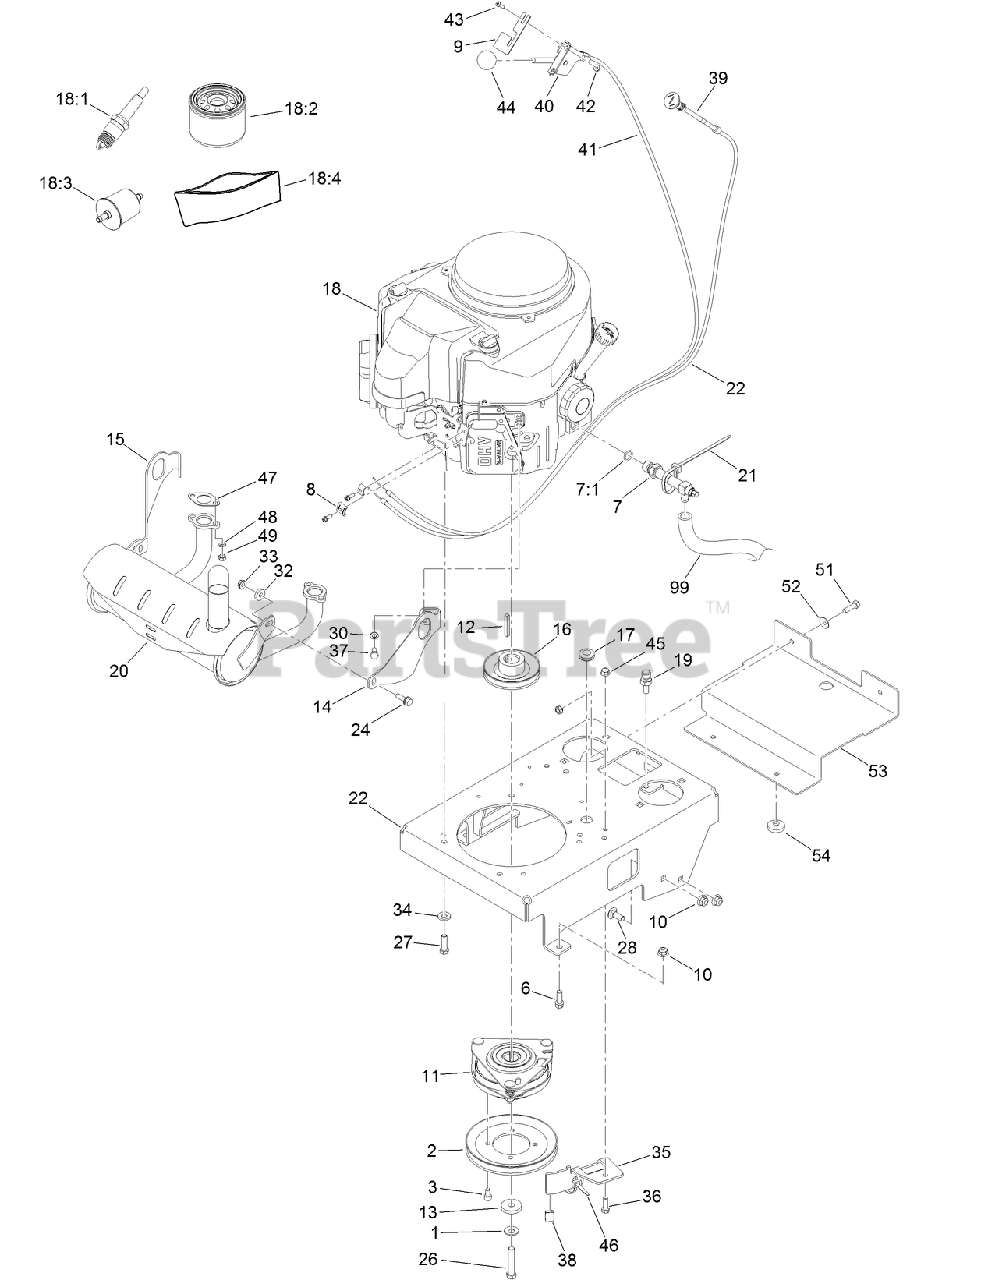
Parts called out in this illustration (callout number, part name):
1	WASHER-SPRING
2	PULLEY
3	SCREW-HSH
7	DRAIN-OIL, VALVE, KAW
7:1	O-RING
8	CLAMP-CABLE
9	PLATE-SET, THROTTLE
10	NUT-HF, NI
11	CLUTCH/BRAKE ASM
12	KEY-SQUARE
13	WASHER
14	BRACKET-MUFFLER, LH
15	BRACKET-MUFFLER, RH
16	PULLEY
17	GROMMET
18:1	SPARK PLUG
18:2	FILTER-OIL
18:3	FILTER-FUEL
18:4	ELEMENT-FILTER, AIR
19	ANCHOR-SPRING, SHORT
20	MUFFLER
21	TIE-CABLE
22	COVER-ENGINE
24	SCREW-HHF
26	SCREW-HH
27	SCREW-HH
28	BOLT-CARR
30	WASHER-LOCK
32	SPACER
33	NUT-HF
34	WASHER-BELLEVILLE
35	BRACKET-CLUTCH STOP
36	SCREW-HH
37	SCREW-HH
38	BUMPER
39	CONTROL-CHOKE, PUSH / PULL
40	LEVER-CONTROL
41	CABLE-CONTROL
42	NUT-LOCK, FLANGE
43	SCREW-TORX
44	KNOB-BALL
45	NUT-HF, NI
46	TIE-CABLE
47	GASKET-EXHAUST
48	WASHER-LOCK
51	SCREW-HH
52	WASHER-BELLEVILLE
53	BRACKET-PROTECTOR, ENGINE
54	BUMPER-PUSH-IN, RUBBER
99	HOSE-DRAIN, OIL
